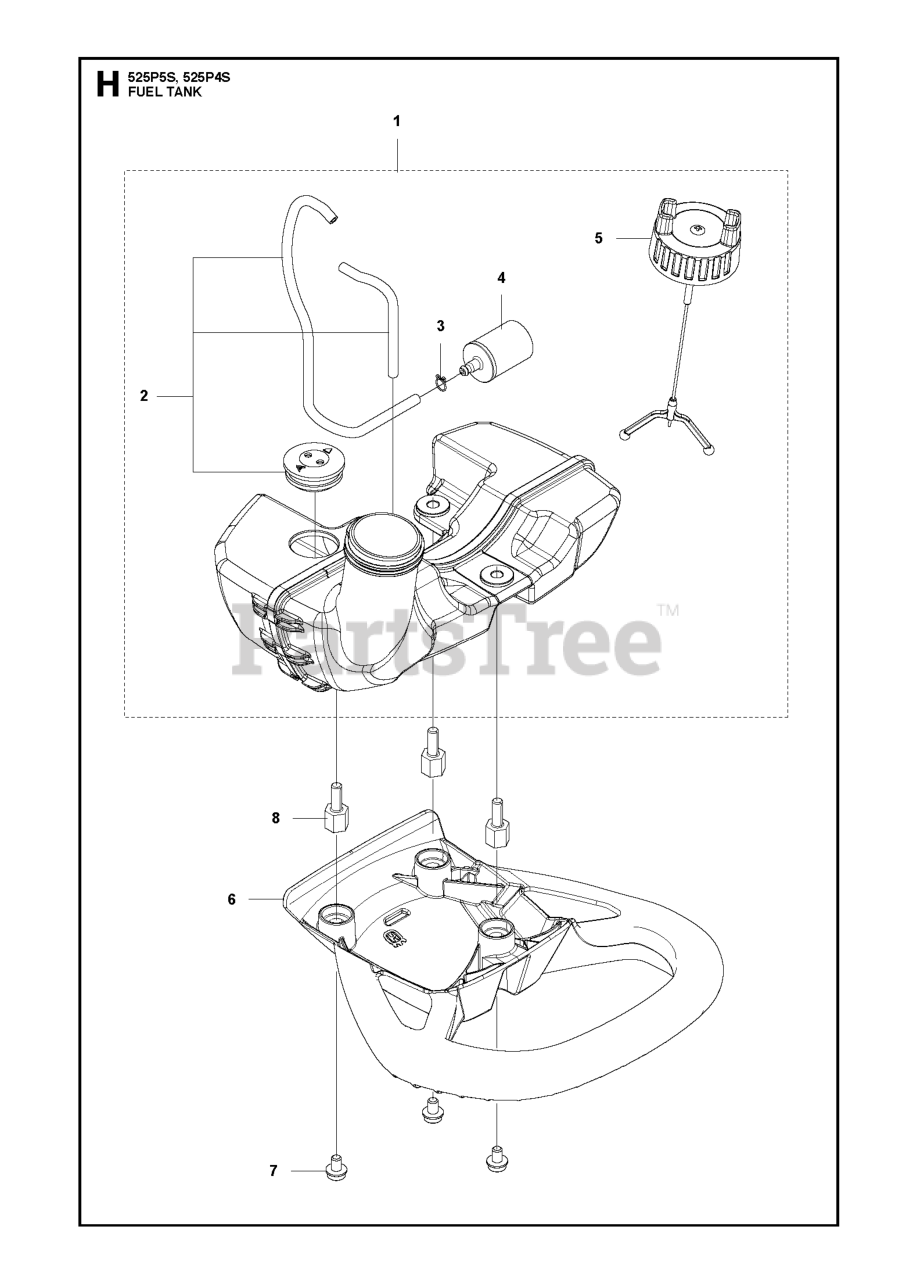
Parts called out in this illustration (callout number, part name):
1	FUEL TANK ASSY
1	FUEL TANK ASSY NBR+PVC
2	HOSE ASSY
4	RP FUEL FILTER
5	GSPH
6	BUMPER ASSY
7	SCREW ITXSCM
8	STUD SCREW M5XM5
